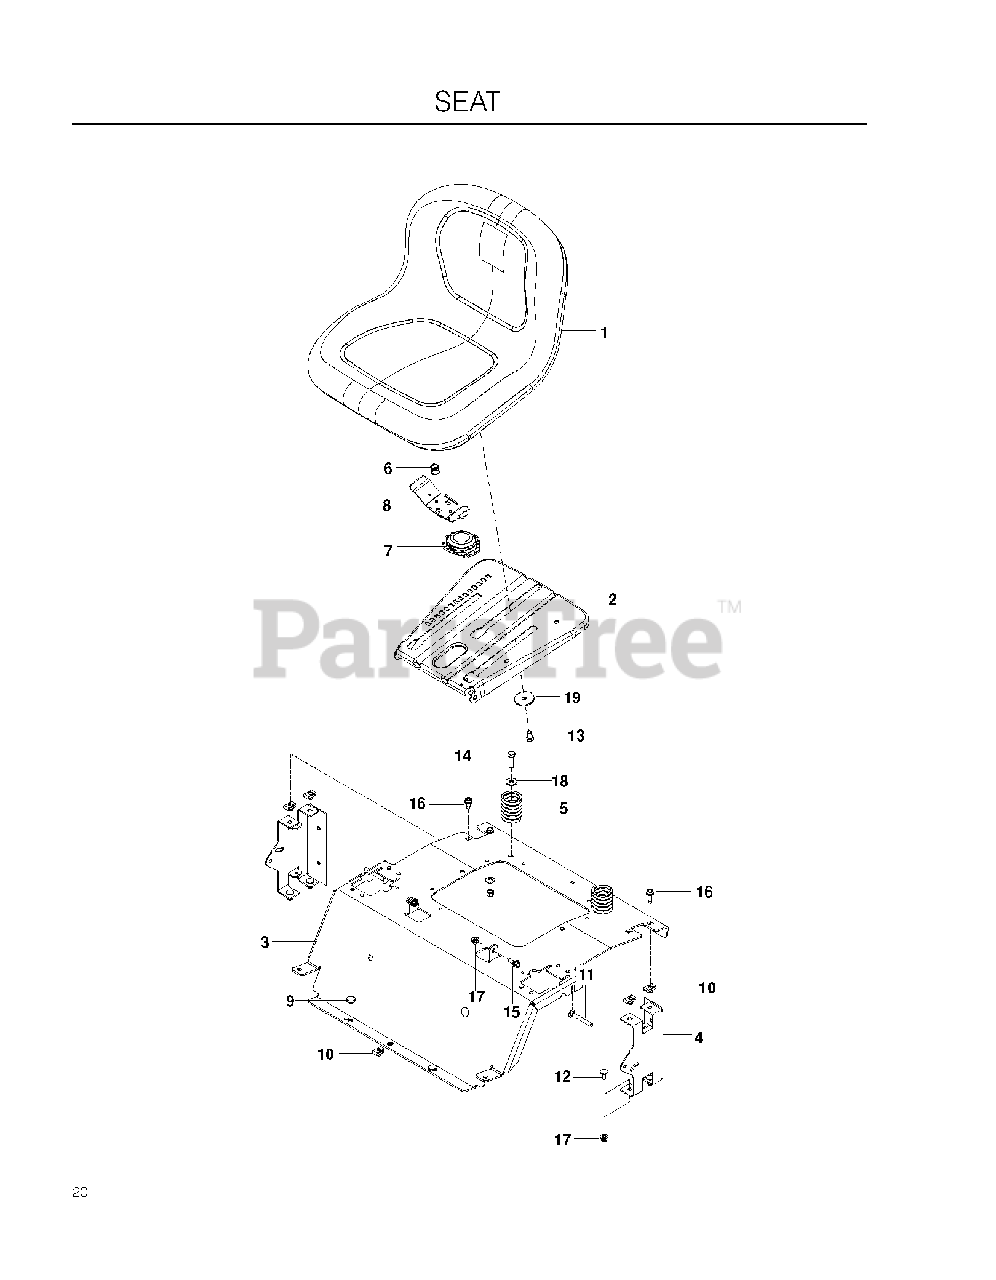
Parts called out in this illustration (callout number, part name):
1	RP SEAT, TH150, GREY, MILSCO
2	PAN.ASM.SEAT.3PT
3	SUPPORT SEAT ORANGE
4	SUPPORT, REAR SEAT, BLACK
5	SPRING, SEAT
6	SPRING.LATCH.SEAT.TEX
7	SWITCH, SEAT N/C
8	HANDLE.SLIDE.SEAT.TEX.BLACK
9	GROMMET, BUMPER
10	U-CLIP 5/16-18 NUT RETAINER
11	RHSNB 5/16-18 X 2-1/2 GR5 ZD
12	BOLT 5/16C X 3/4" CARRIAGE
13	HCS 3/8-16 X 5/8 GR 5 ZD
14	HCS 3/8C X 1 1/4 GR5
15	HCS 5/16C X 1
16	BOLT, SHOULDER
17	BOLT 5/16-18 X 3/4
18	NUT 5/16 NYLOC
19	5/16-18 NYLOC FLANGE NUT
20	RP WASHER 3/8 FLAT
21	WASHER, 3/8 SPEC
22	FLAT WASHER 5/16 SAE
